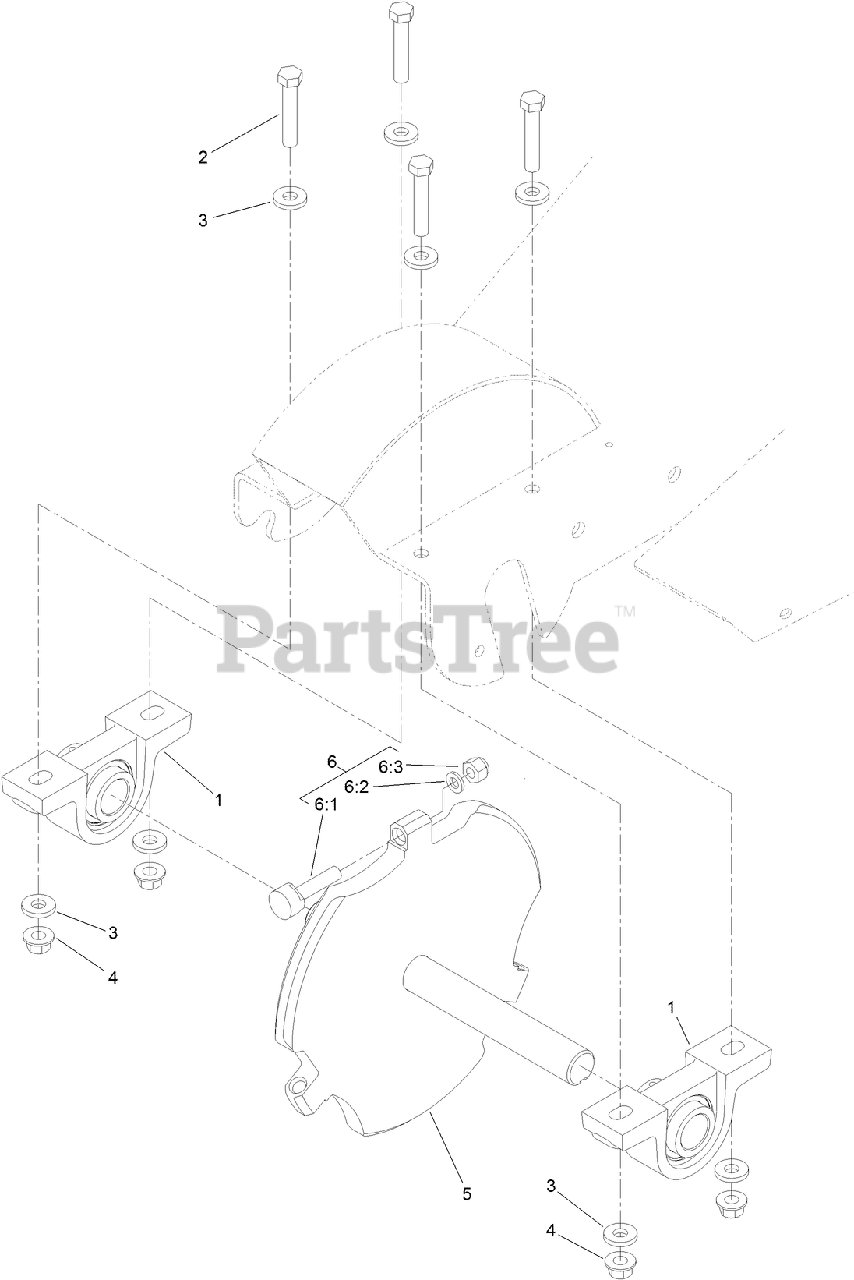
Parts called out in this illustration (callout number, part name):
1	BEARING ASM
2	SCREW-HH
3	SPACER
4	NUT-FLANGE, LOCK
5	3 TOOTH WHEEL/SHAFT
6	GRINDER TOOTH KIT (SINGLE)
6	GRINDER TOOTH KIT (3-PACK)
6	GRINDER TOOTH KIT (6-PACK)
6:1	TOOTH-GRINDER
6:2	WASHER-HARDENED
6:3	NUT-LOCK
